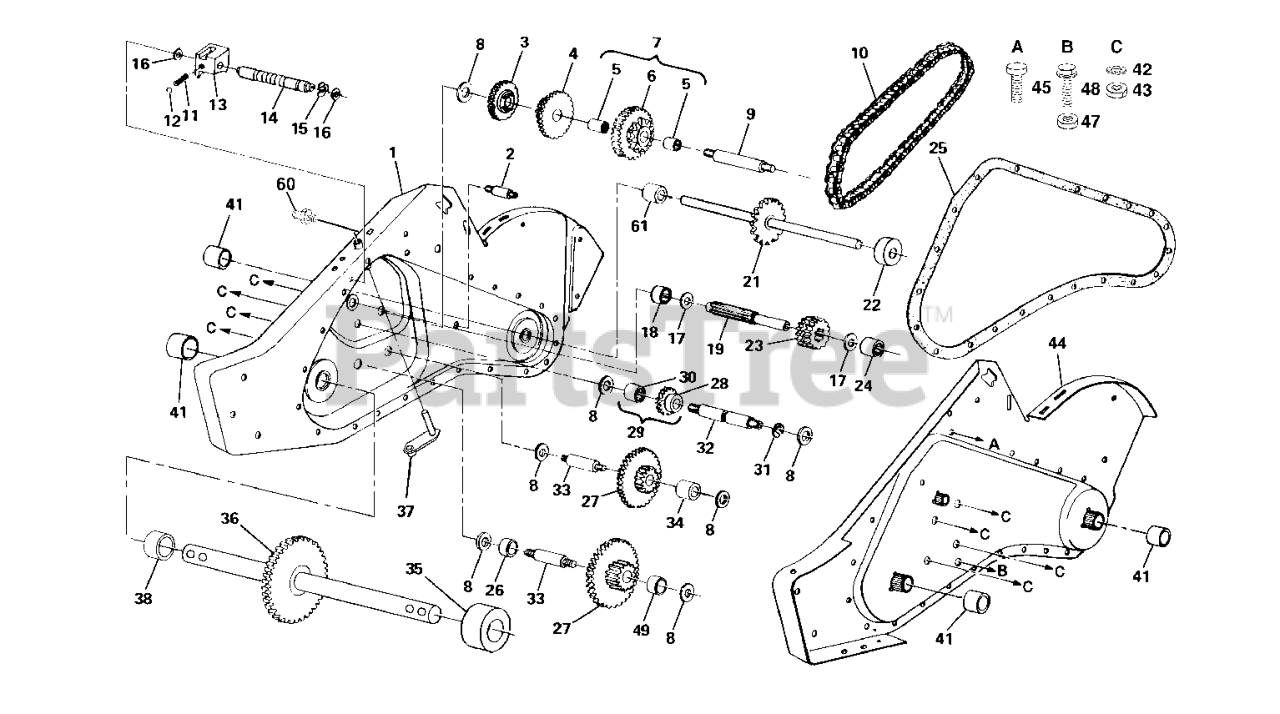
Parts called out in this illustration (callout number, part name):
1	GEARCASE ASM.RH.W/BEARING 2002
2	SPACER.GEARCASE
3	GEAR.REVERSE.8HP
5	BEARING.NEEDLE.CRT
6	SPROCKET ASMBLY, TINE
7	SPROCKET ASMBLY W/BEARINGS
9	SHAFT.REDUCTION.TILLER
10	CHAIN.ROLLER.TILLER
11	SPRING-SHIFT CRT
12	STEEL BALL KIT
13	SHIFT FORK TI
14	SHAFT.SHIFT.1.00 PINION
16	WASHER, SEAL (2 2)
17	THRUST WASHER
18	BEARING TI
19	SHAFT INPUT
21	SHAFT.ASM.TINE.21
22	SPACER 1.008X1-3/4X.645
23	GEAR.PINION
24	NEEDLE BRNG LT
25	GASKET.GEARCASE.8HP
27	GEAR, CLUSTER CRT
28	REVERSE GEAR
29	GEAR ASMBLY, REVERSE IDLER
30	NEEDLE BEARING TI
32	SHAFT, REVERSE IDLER
33	SHAFT, REDUCTION
34	SPACER.765 X 1.12 X .380.
35	SPACER, GROUND DRIVE RH
36	SHAFT ASSY CRT
37	BRACKET ASM.SHIFT.CRT
38	SPACER, GROUND DRIVE
41	SEAL ASM, OIL
42	LOCKWASHER
43	NUT.ASF.HEX.7/16
44	GEARCASE ASM.LH.W/BEARING 2002
45	SCREW
47	NUT
48	SCREW 5/16-18X4
60	FITTING.GREASE.TAPERED
61	SPACER.1.015 X 1.50 X .765
